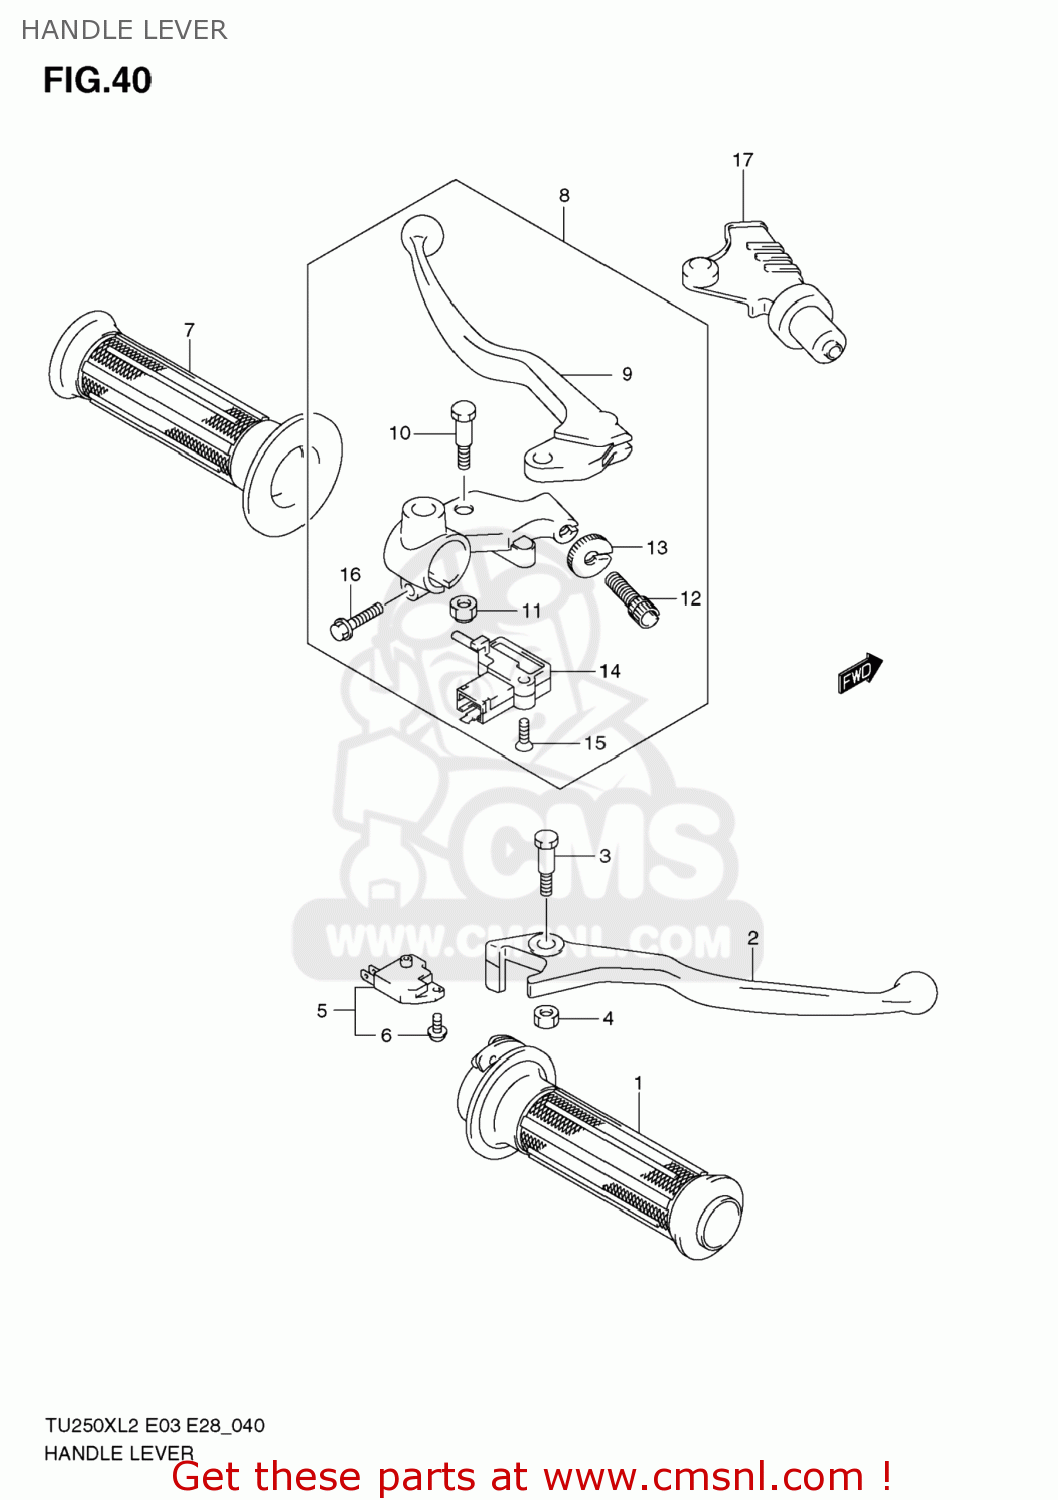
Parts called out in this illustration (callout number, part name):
1	GRIP,THROTTLE(BLACK)
2	LEVER,FR BRAKE
3	BOLT,BRAKE LEVER PIVOT
4	NUT,LEVER PIVOT
5	SWITCH ASSY,ST
6	SCREW
7	GRIP,L
8	LEVER ASSY,CLUTCH
9	LEVER,CLUTCH
10	BOLT,LEVER PIVOT
11	NUT
12	ADJUSTER,WIRE
13	NUT,LOCK
14	SWITCH,CLUTCH
15	SCREW
16	BOLT
17	COVER,CLUTCH LEVER
